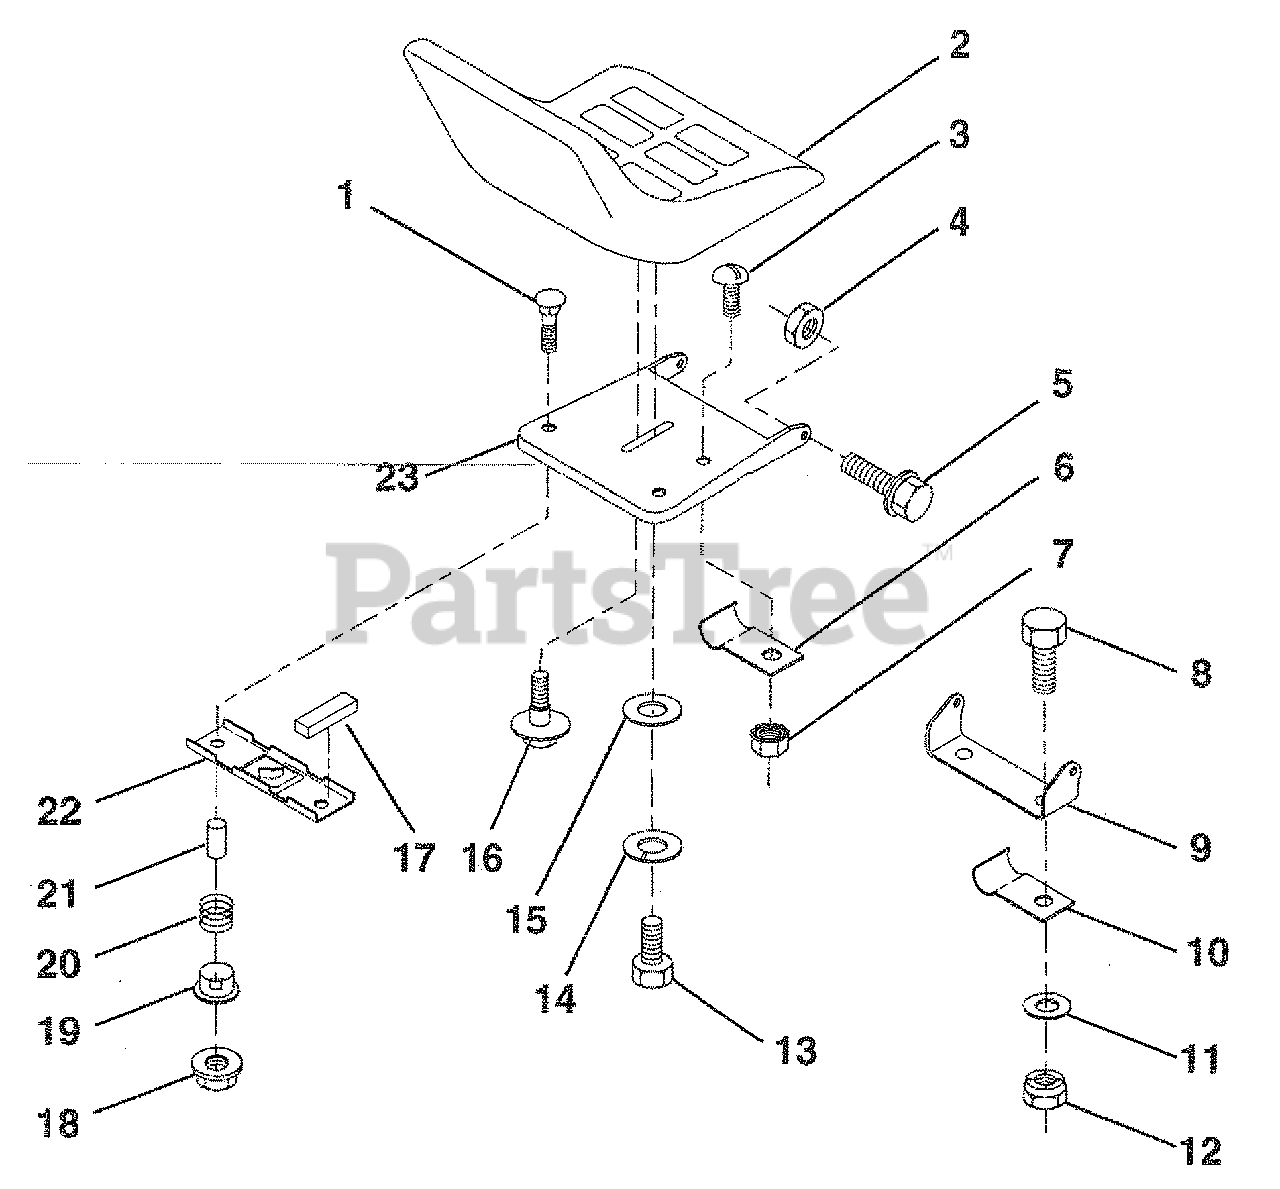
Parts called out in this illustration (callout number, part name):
1	Bolt, Carriage 1/4-20 x 1-3/8
2	Seat
3	Screw, Siotted Pan Head #10-32 x 1/2
4	Nut, Crownlock 5/16-18
5	Bolt, Shoulder 5/16-18 UNC
6	Clip, insulated
7	Nut, Keps #10-32 UNF
8	Bolt, Fin Hex 3/8-16 UNC x 3/4
9	Bracket, Pivot Seat
10	Clip, Insulated
11	Washer 12/32 x2 x 10 Ga.
12	Nut, Crownlock 3/8-16 UNC
13	Bolt, Fin Hex 1/2-13 x 7/8 Gr. 5
14	Washer, Lock Hvy Hlcl Spr 1/2
15	Washer, 17/32 x 1-3/16 x 12 Ga.
16	Bolt Shoulder
17	Strip, Foam
18	Nut, Hex Large Flange Lock
19	Bushing, Snap
20	Spring, Compression
21	Spacer, Split 28 x .96
22	Bracket, Switch, Mounting
23	Pan, Seat
